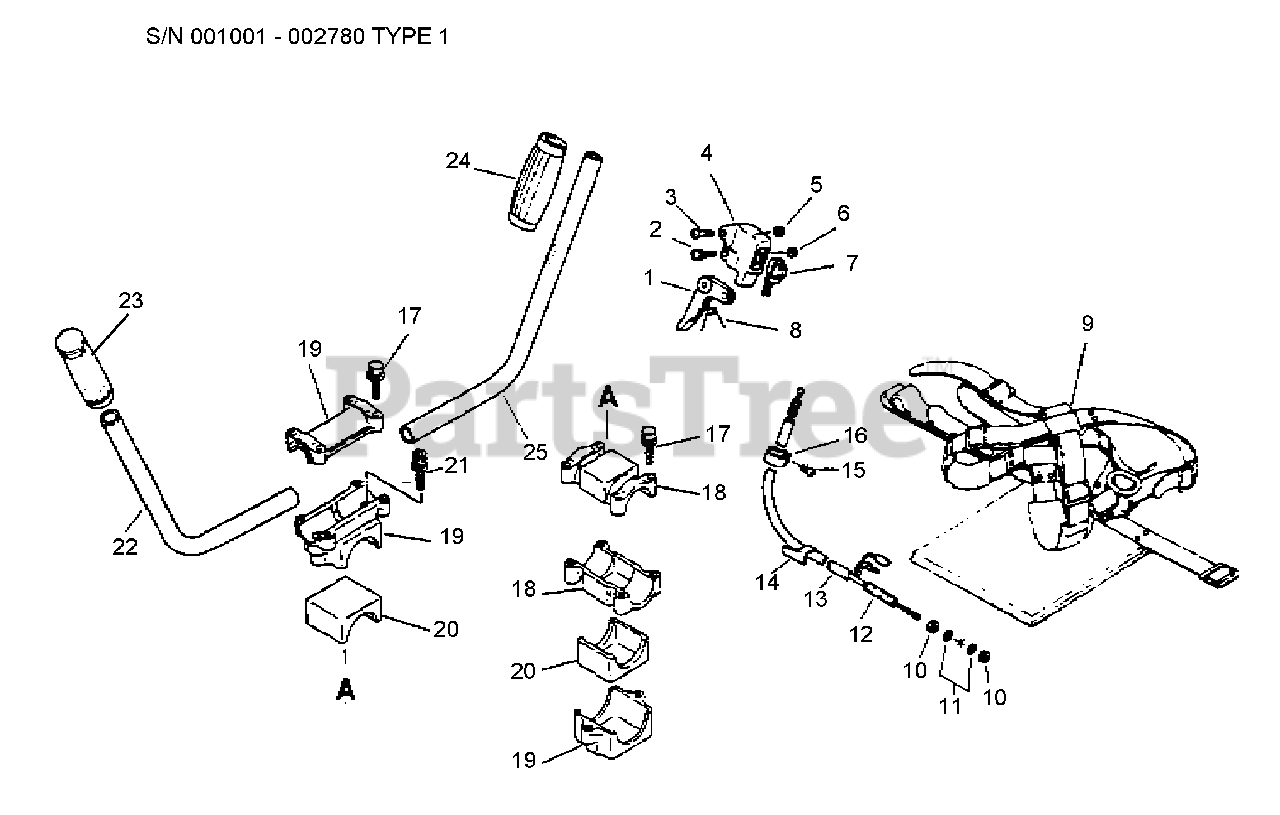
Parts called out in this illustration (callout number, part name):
1	TRIGGER, THROTTLE
2	SCREW 5×30
4	BRACKET, THROTTLE
5	LOCKNUT - 5
6	NUT M5
7	SWITCH, ON-OFF
9	SHOULDER STRAP ASSY
9	HARNESS, SHOULDER
10	NUT, HEX M6
11	WASHER 6.5×11.5×0.8
12	CABLE, THROTTLE
15	SCREW 5×10
17	BOLT - 5×25
18	BRACKET KIT
19	BRACKET ASSY
20	CUSHION
21	BOLT 5×25
22	HANDLE, LEFT
23	GRIP, HANDLE
